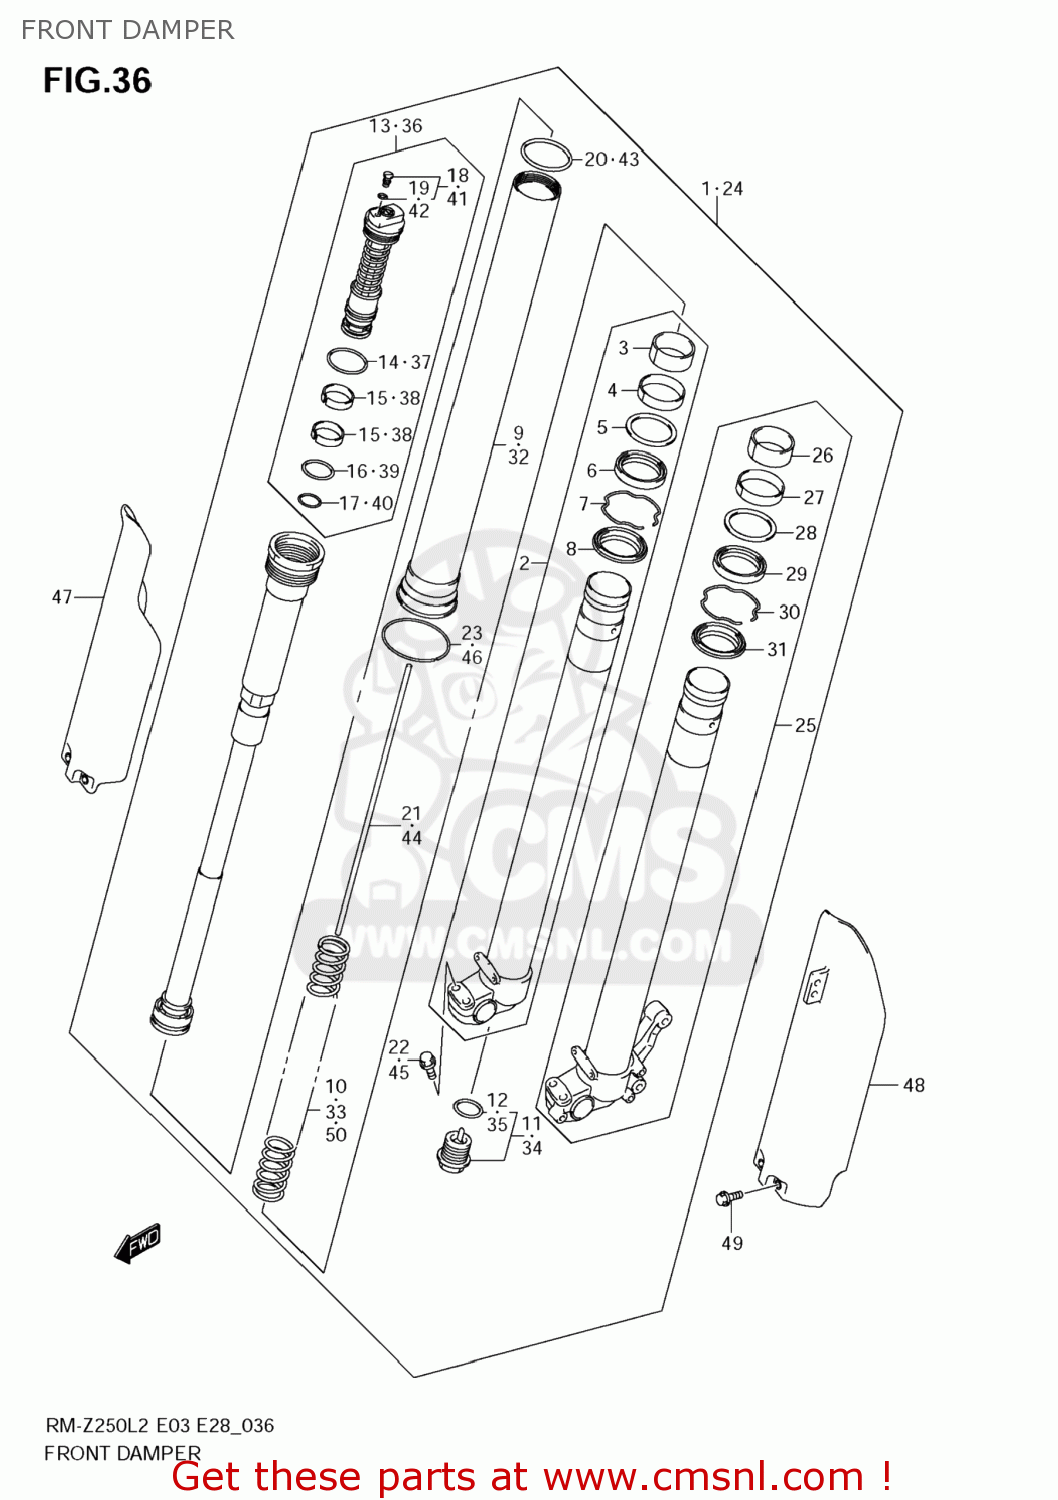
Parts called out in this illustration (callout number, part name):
1	DAMPER ASSY,FR FORK,R
2	TUBE,INNER,R
3	BUSH
4	BUSH,GUIDE
5	SPACER,SEAL
6	SEAL,OIL
7	RING,OIL SEAL STOPPER
8	SEAL,DUST
9	TUBE,OUTER
10	SPRING,FR(K=0.47)
11	BOLT,CTR
12	O RING
13	BOLT,FORK
14	O RING
15	BUSH
16	O RING
17	O RING
18	BOLT,PLUG
19	O RING,PLUG
20	O RING
21	ROD,PUSH
22	BOLT
23	STOPPER,RING
24	DAMPER ASSY,FR FORK,L
25	TUBE,INNER,L
26	BUSH
27	BUSH,GUIDE
28	SPACER,SEAL
29	SEAL,OIL
30	RING,OIL SEAL STOPPER
31	SEAL,DUST
32	TUBE,OUTER
33	SPRING,FR(K=0.47)
34	BOLT,CTR
35	O RING
36	BOLT,FORK
37	O RING
38	BUSH
39	O RING
40	O RING
41	BOLT,PLUG
42	O RING,PLUG
43	O RING
44	ROD,PUSH
45	BOLT
46	STOPPER,RING
47	PROTECTOR,FRON
48	PROTECTOR,FRON
49	BOLT(6X10)
50	SPRING,FR(K=0.45)
